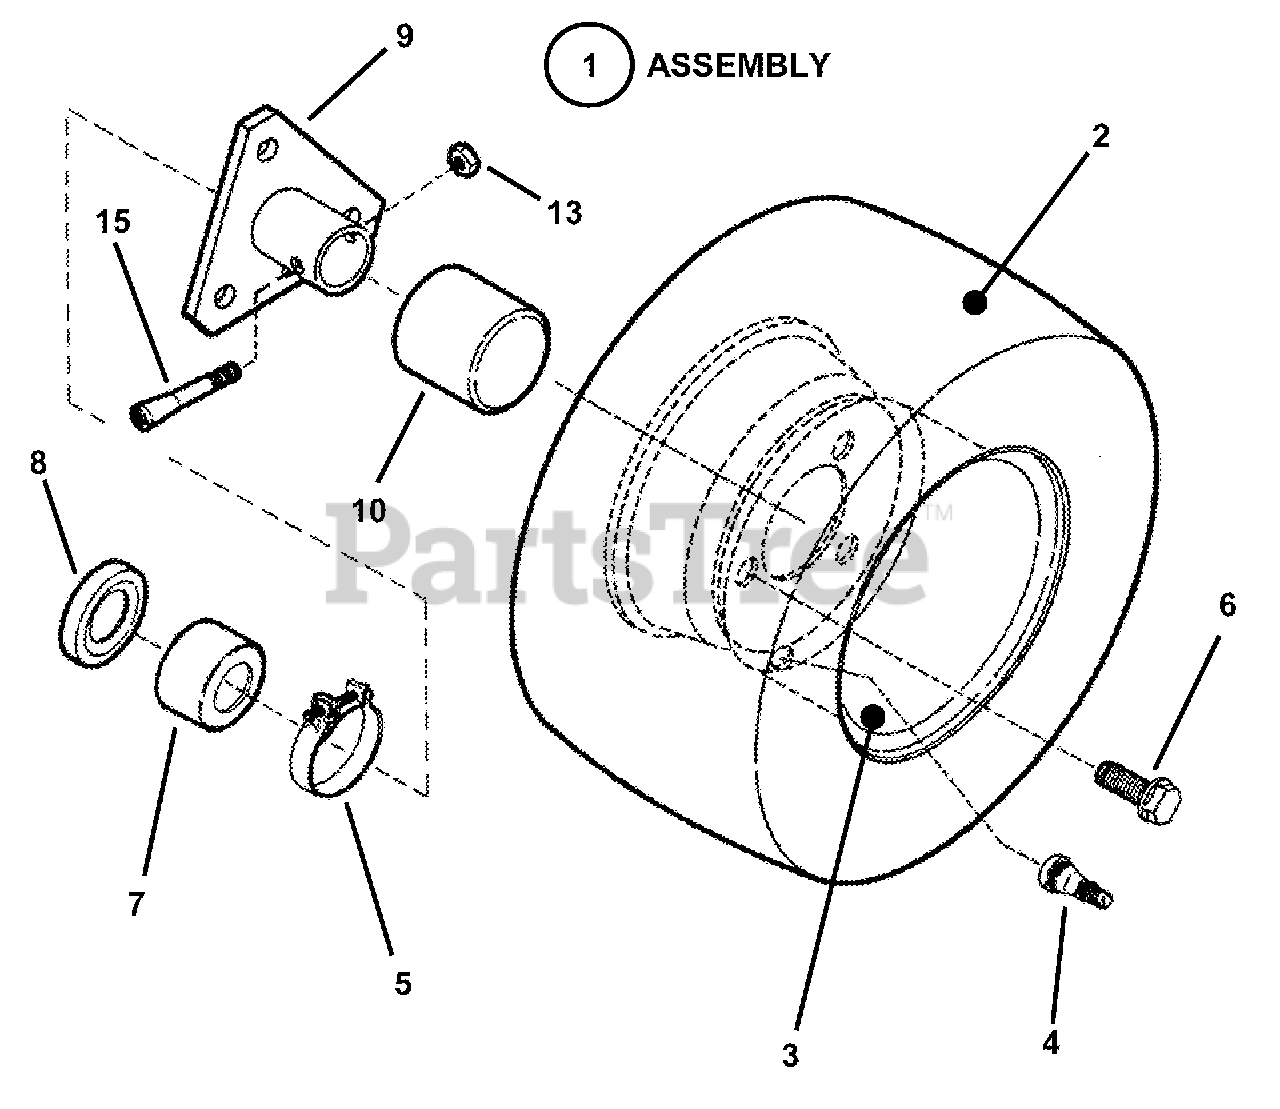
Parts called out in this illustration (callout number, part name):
1	ASSEMBLY, Rear Tire & Rim
2	TIRE, 16-6.50 x 8
3	RIM, Extra Wide, (For 16/7.50 x 8 Tire)
4	VALVE, Air (Snap-in)
5	CLAMP, Right Hand
6	BOLT, 1/2-20 x 3/4" Lug
7	BOOT, Right Hand
8	SEAL, Oil
9	HUB, Rear Wheel R. H. (Weldment)
10	CAP, Hub
13	NUT, 5/16-24 Hex Center Lock
15	BOLT, 5/16-24 x 2" Tapered (Right Hand)
